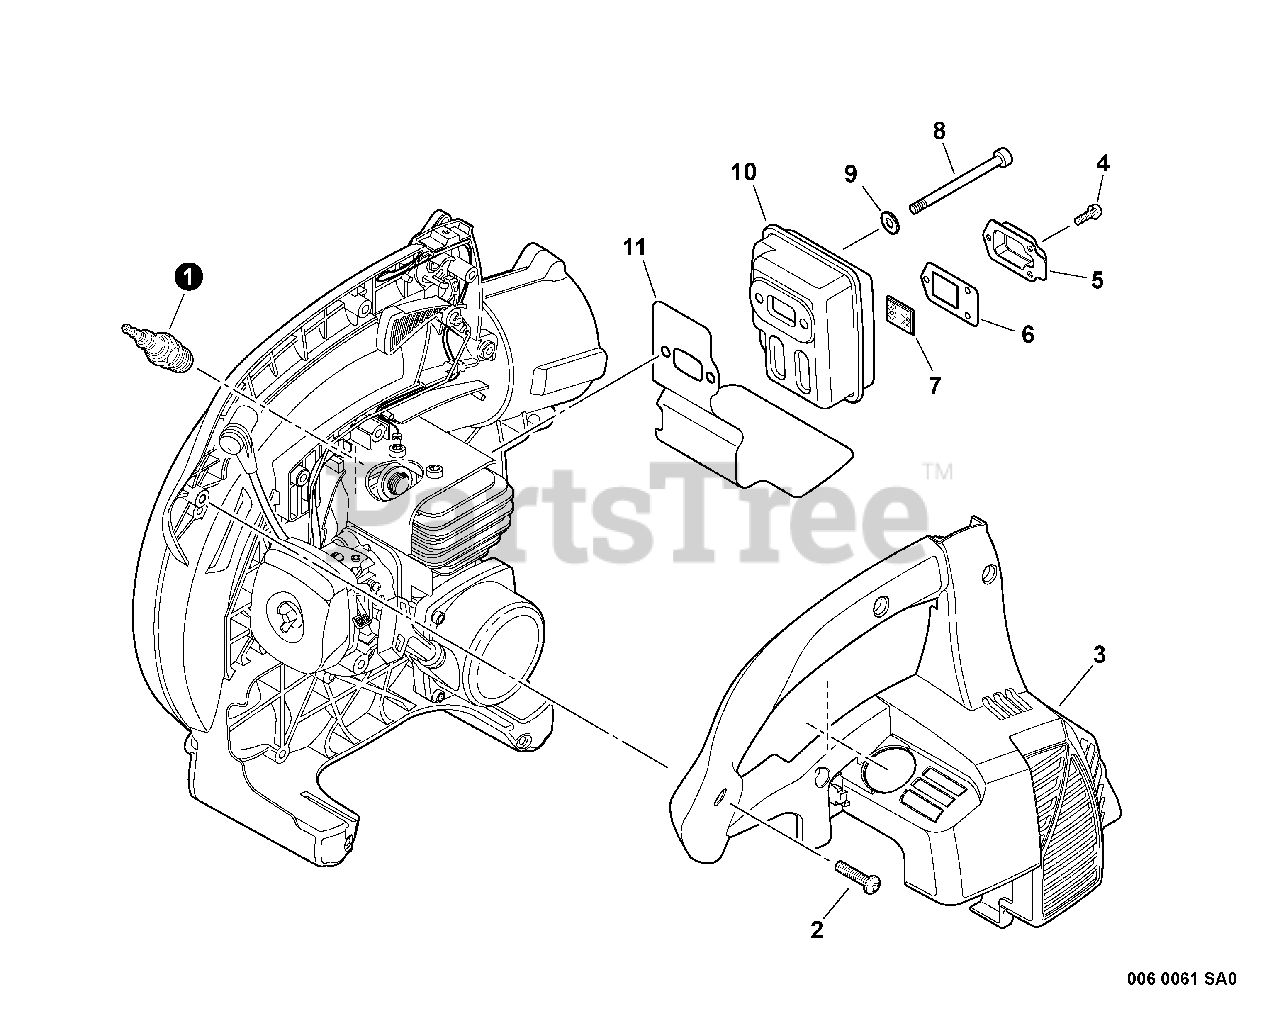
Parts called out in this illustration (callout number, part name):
1	SPARK PLUG -- BPM-8Y
2	SCREW - 5X20
3	COVER, ENGINE
4	SCREW - 4X10
5	GUIDE, EXHAUST - OUTER
6	GASKET, EXHAUST
7	SCREEN, SPARK ARRESTOR
8	SCREW - 5X55
9	WASHER - 5
11	SHIELD, EXHAUST
